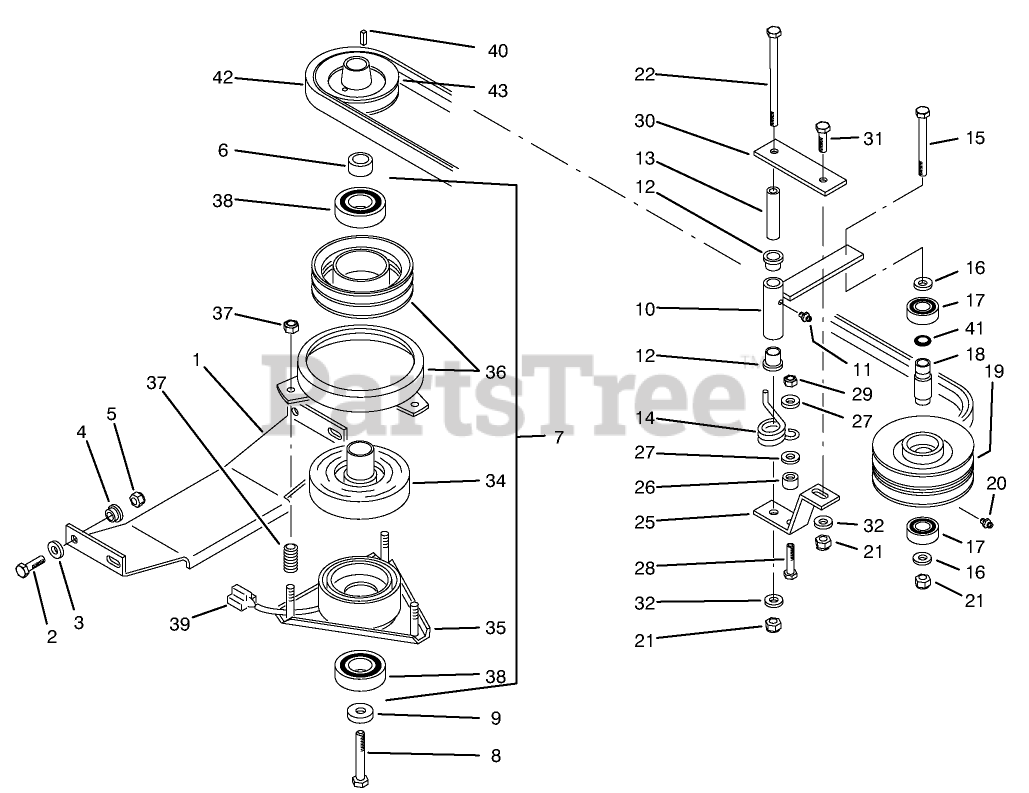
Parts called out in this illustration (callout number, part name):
1	BRACKET CLUTCH ST R
2	SCREW-HH
3	WASHER-PLAIN
4	BUSHING
5	NUT-LOCK, NI
6	SPACER
7	Electric Clutch Assembly (Incl. Ref. # 34-39)
8	SCREW-HH
9	WASHER
10	Arm-Idler
11	Fitting-Grease
12	BUSHING
13	SPACER
14	SPRING-TORSION
15	SCREW-HH
16	WASHER-SPACER
17	BEARING-BALL
18	SPACER-PTO IDLER
19	PULLEY 2- GROOVE
20	FITTING-GREASE
21	NUT-LOCK, NI
22	SCREW-HH
25	Bracket-Idler
26	Spacer
27	WASHER-FLAT
28	SCREW-HH
29	NUT-LOCK, NI
30	Plate
31	SCREW-HH
32	WASHER-FLAT
34	ROTOR ASSEMBLY
35	Field Assembly (Incl. Ref. #38 & 39)
36	Armature Assembly (Incl. Ref. #38)
37	ACCESS SPRING & NUT
38	BEARING-ELEC CLUTCH
39	CONNECTOR BODY B
41	O RING
42	V-BELT
43	PULLEY
